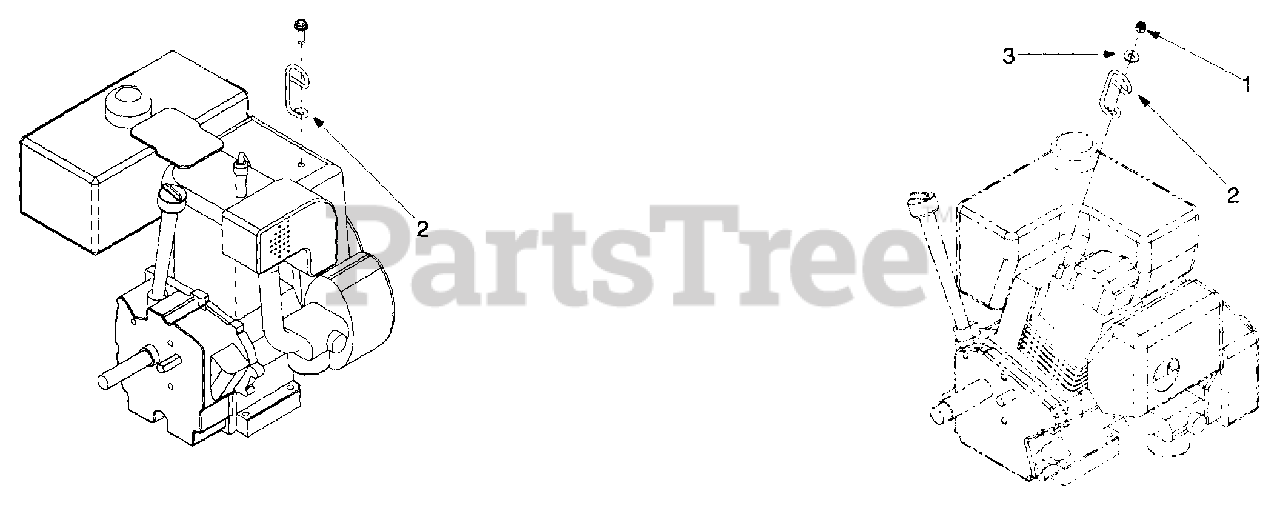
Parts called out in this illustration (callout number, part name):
1	Hex Lock Nut: 1/4-20
2	Cable Guide
3	Flat Washer
